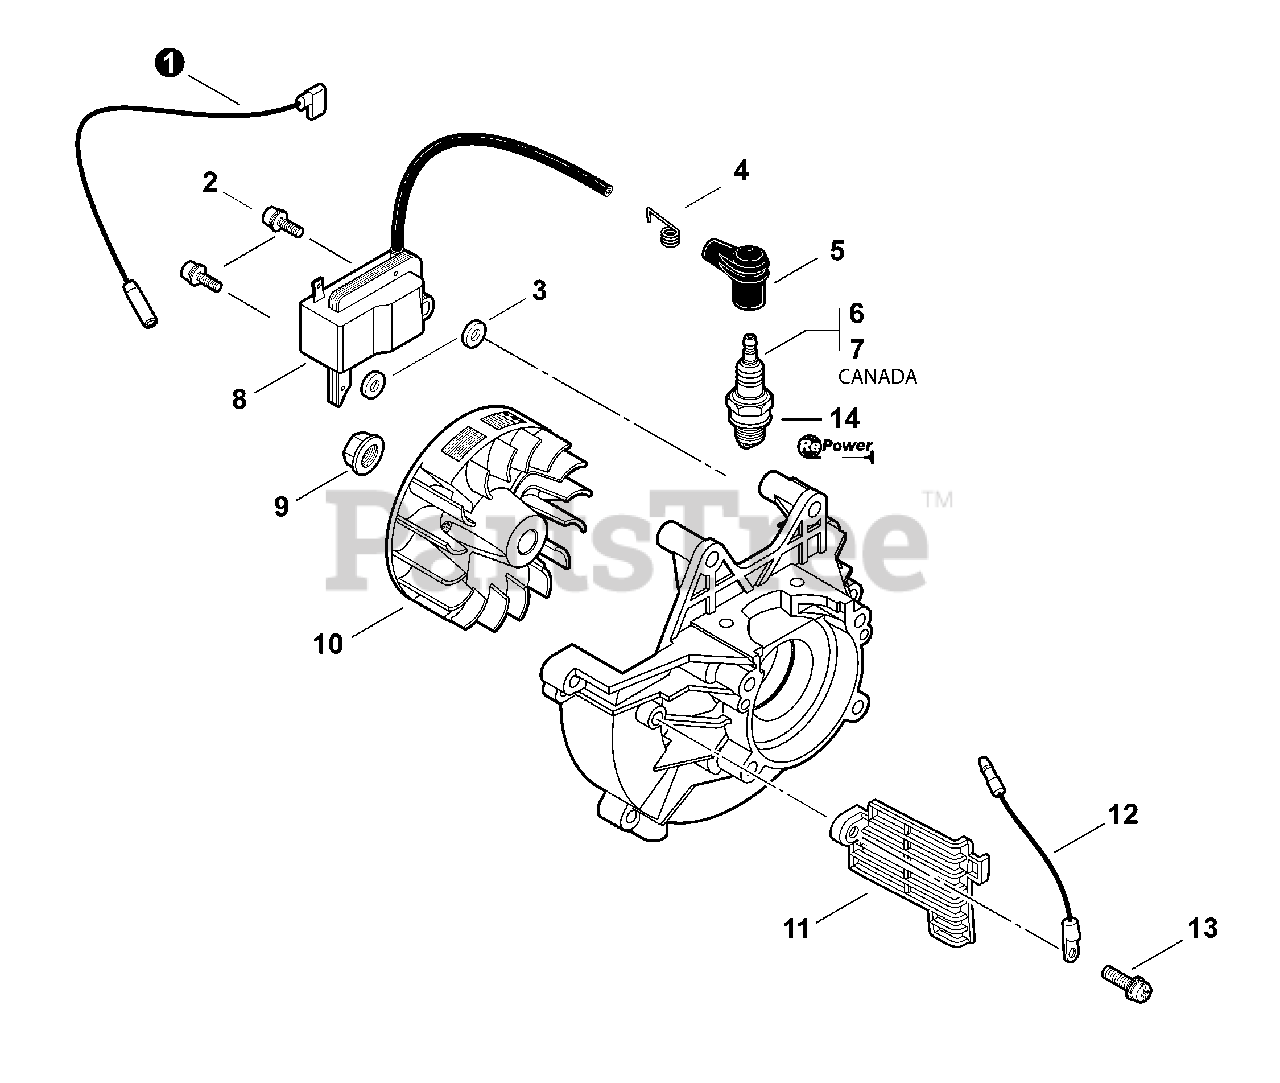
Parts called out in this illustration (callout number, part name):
1	LEAD - IGNITION
2	BOLT 5×20
3	SPACER 5
4	TERMINAL, SPARK PLUG
5	CAP, SPARK PLUG
6	SPARK PLUG - BPM8Y
7	SPARK PLUG - BPMR8Y
8	COIL, IGNITION
9	NUT, FLANGE M8
10	FLYWHEEL
11	SHIELD, DEBRIS
12	LEAD - GROUND
13	SCREW 5×10
14	TUNE-UP KIT - REPOWER
